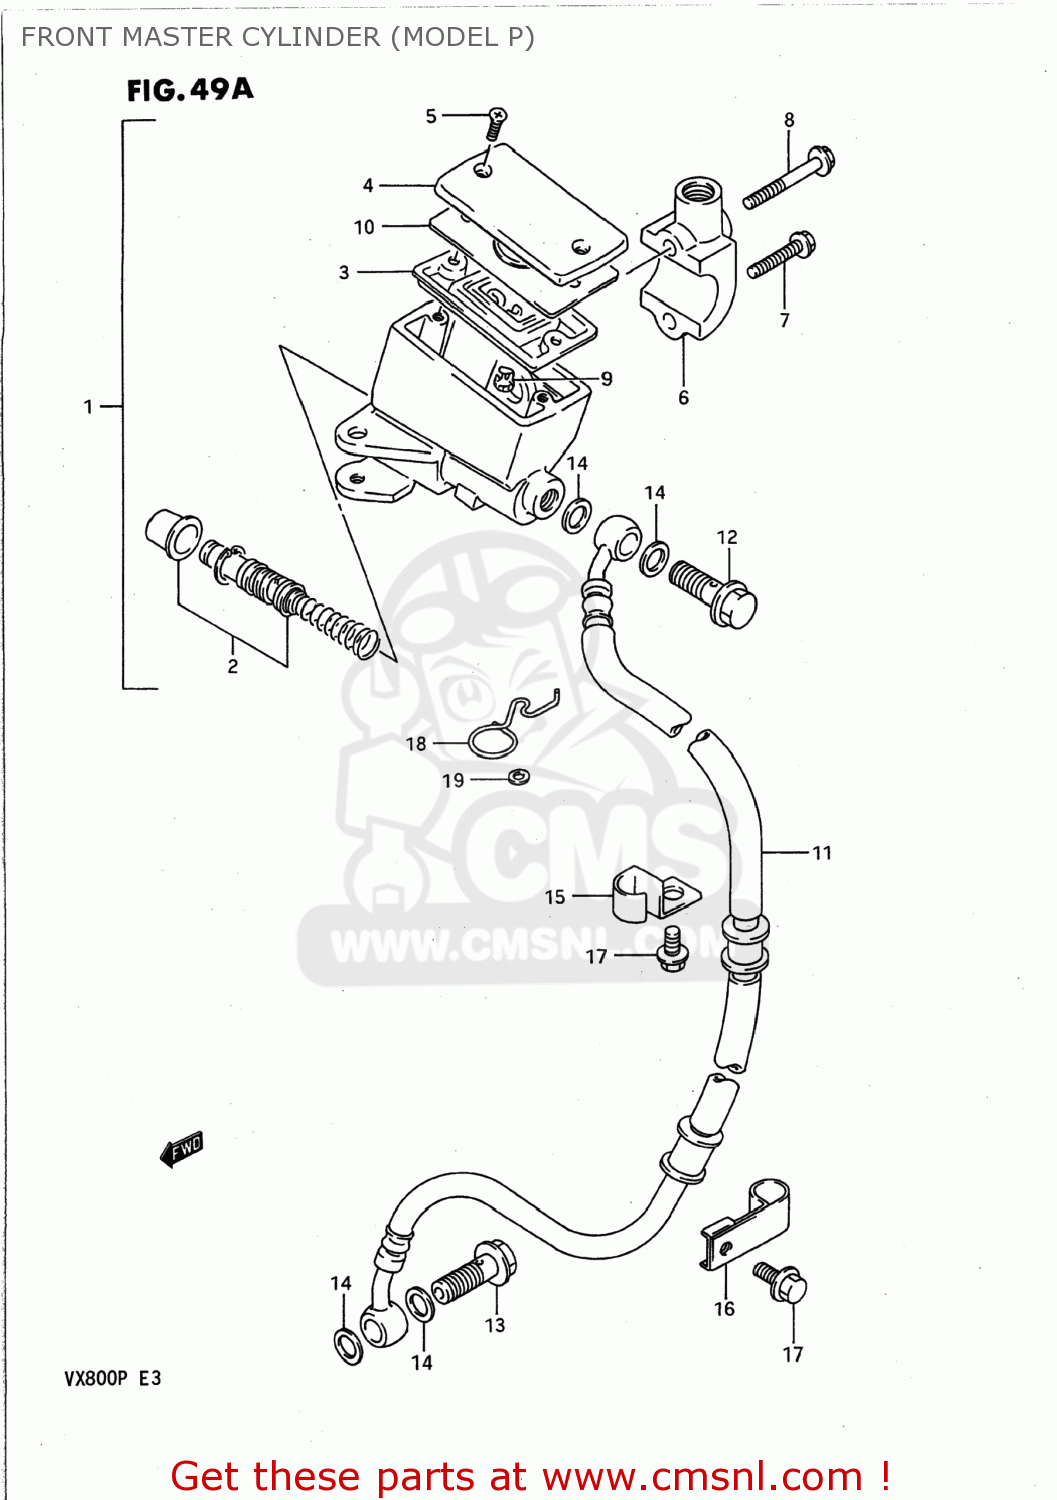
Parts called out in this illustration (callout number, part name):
1	CYLINDER ASSY,FR MASTER
2	PISTON/CUP SET
3	4
4	CAP
5	SCREW
6	HOLDER
7	BOLT(6X25)
8	BOLT(6X38)
9	PROTECTOR
10	PLATE,DIAPHRAGM
11	HOSE COMP,FRONT BRAKE
12	BOLT UNION
13	BOLT 10X1.25X24
14	WASHER(10X15X1.5)
15	CLAMP,FR BRAKE HOSE NO.1
16	CLAMP,FRONT BRAKE NO.2
17	BOLT 6X12
18	GUIDE,FRONT BRAKE HOSE
19	WASHER
